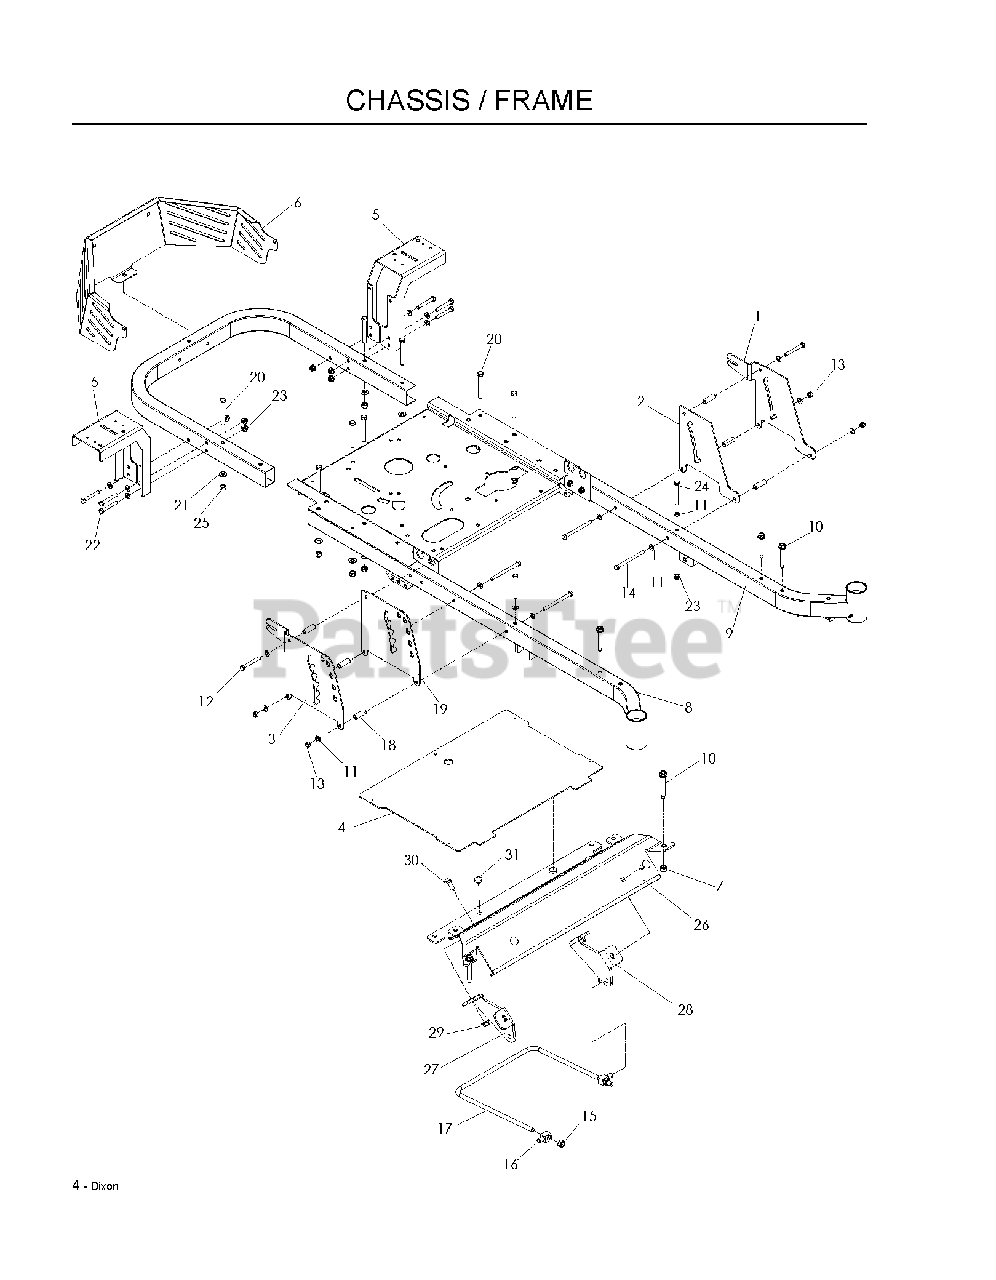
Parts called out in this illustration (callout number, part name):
1	PLATE, OUTER BRAKE, BLACK
2	PLATE, BRAKE LATCH, BLACK
4	PLATE, FOOT W/DECALS KZ
5	SUPPORT, FENDER, BLACK
6	GUARD, REAR, BLUE
8	FRAME, RT, BLUE
9	FRAME, LT, BLUE
10	ENGINE BOLT, SPECIAL
11	FLAT WASHER 5/16 SAE
12	BOLT 5/16C X 2 1/2
13	NUT 5/16 NYLOC
14	HCS 5/16C X 4
15	7/16-14 HEX NUT W/NYL RING ZD
17	LINK, FRONT SUSP.
18	SPACER, .334 ID X .5 OD X 1.5
19	PLATE, DECK HEIGHT, BLACK
20	HCS 3/8C X 3
21	WASHER 3/8 SAE FLAT
22	CAPSCREW
23	5/16-18 NYLOC FLANGE NUT
24	HCS 5/16C X 2-3/4
25	NUT 3/8-16 NYLOC
26	FOOT REST, MED BLUE
27	MOUNT, STRUT, RT, BLK
28	MOUNT, STRUT, LT, BLK
29	NUT 3/8-16 HEX FLG NYLOC ZD
30	RHSNB 3/8C X 1
31	GROMMET, BUMPER
